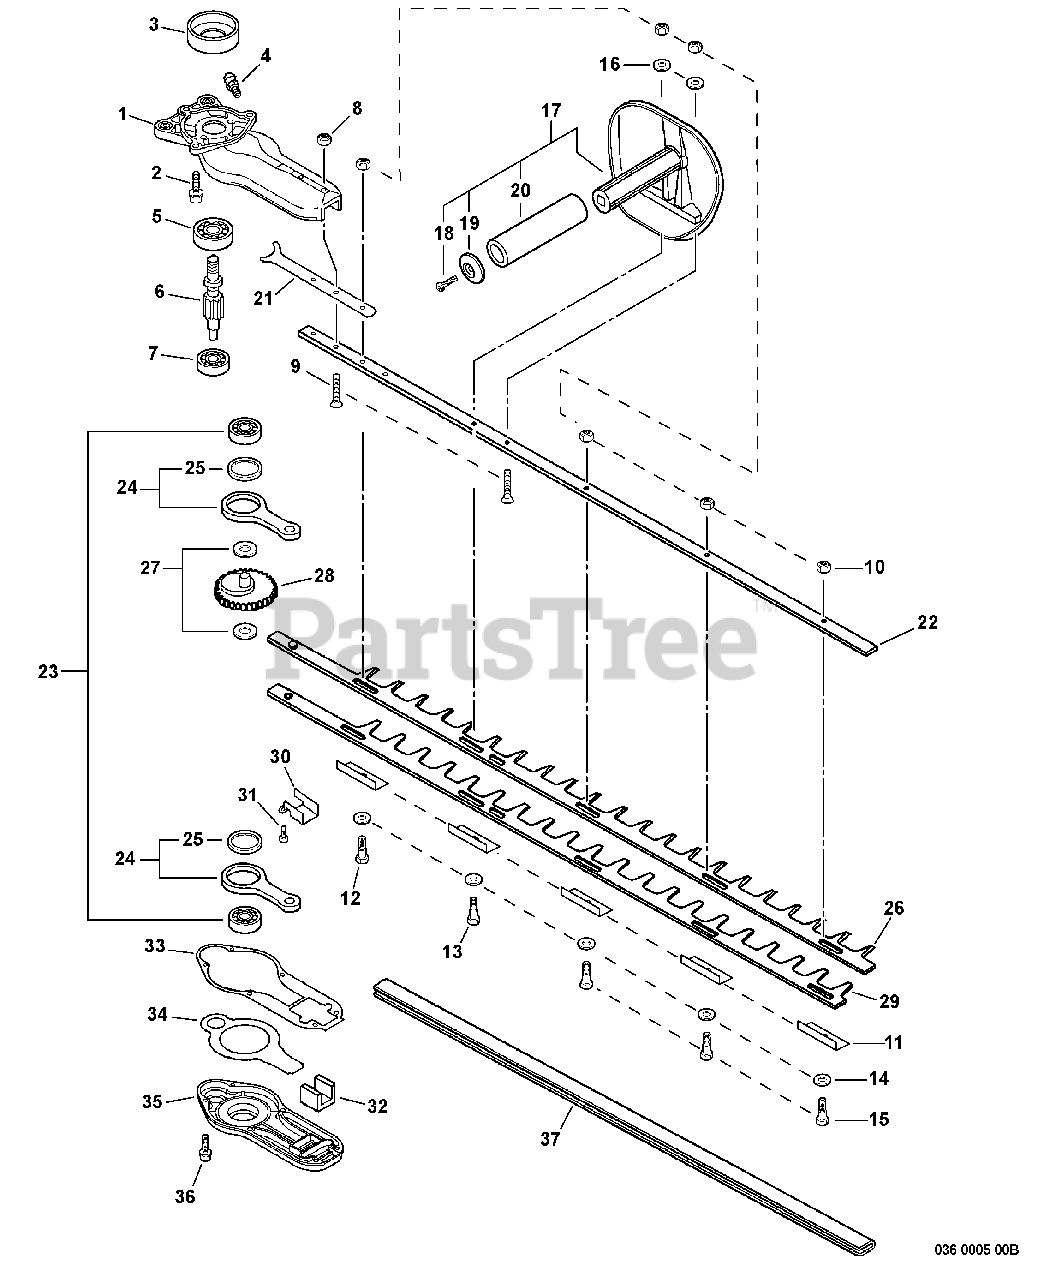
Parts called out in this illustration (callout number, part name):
1	CASE, GEAR - UPPER
2	SCREW - 6X18
3	DRUM, CLUTCH
4	FITTING, GREASE
5	BEARING, BALL - 6200
6	GEAR - SPUR
7	BEARING, BALL - 608ZZ
8	NUT - 6 -- FLANGE
9	SCREW - 6X30
10	LOCKNUT - 6
11	INSULATOR
12	BOLT - 6
16	WASHER - 6
17	HANDLE ASSY - FRONT
18	SCREW - 5X14
20	GRIP, HANDLE
22	SUPPORT, BLADE - 30" (76cm)
23	BEARING, BALL - 6200
24	ROD, CONNECTING
25	BEARING, NEEDLE
26	BLADE - 30" (76mm) -- UPPER
27	WASHER - 10
28	GEAR - SPUR
29	BLADE - 30" (76mm) -- LOWER
30	GUIDE, BLADE
31	SCREW - 4X16
33	GASKET, GEAR CASE
34	PLATE, GEAR CASE
35	CASE, GEAR - LOWER
36	SCREW - 4X16
37	COVER, BLADE
